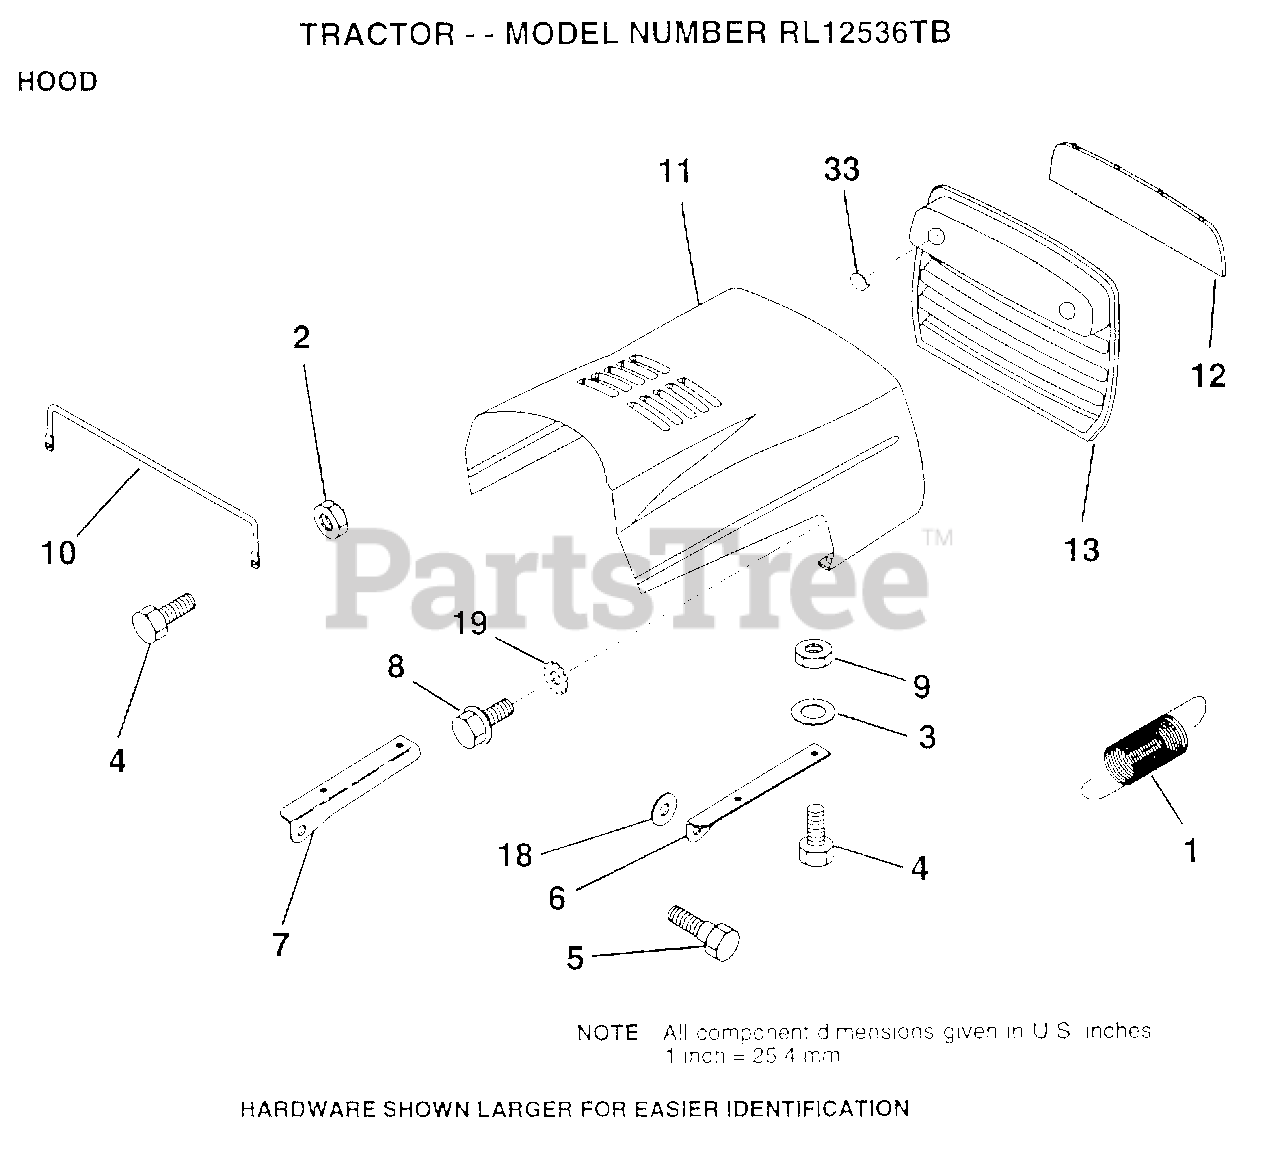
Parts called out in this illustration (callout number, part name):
1	EXT SPRING
2	NUT HXKEP 1/4X20
3	WASHER
5	BOLT.SHLD.5/16-18
6	BRKT HOOD RH
7	BRKT HOOD LH
8	SCREW SLTD HXHD
9	NUT
10	"BRACE,HOOD"
11	HOOD
12	LENS
13	GRILL
18	WASHER
19	LOCKWASHER GT
